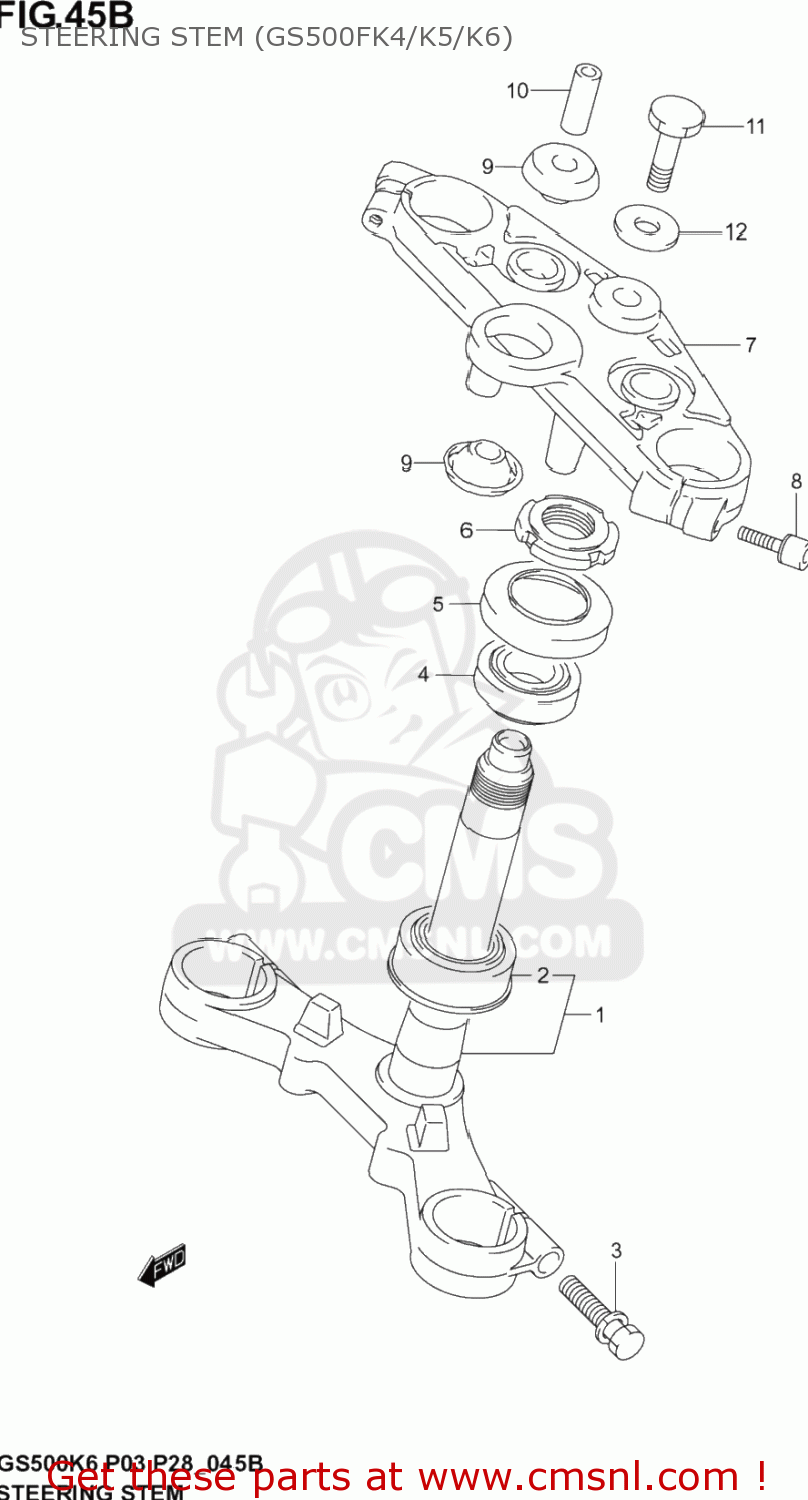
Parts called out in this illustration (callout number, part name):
1	STEM, STEERING
2	BEARING(30X55X17)
3	BOLT,STEERING
4	BEARING(25X47X15)
5	SEAL,STEERING UPR DUST
6	NUT,STEERING STEM(25X44X10)
7	HEAD STEERING
8	BOLT
9	CUSHION, STEM HEAD
10	SPACER, HEAD S
11	BOLT, UPPER
12	WASHER
